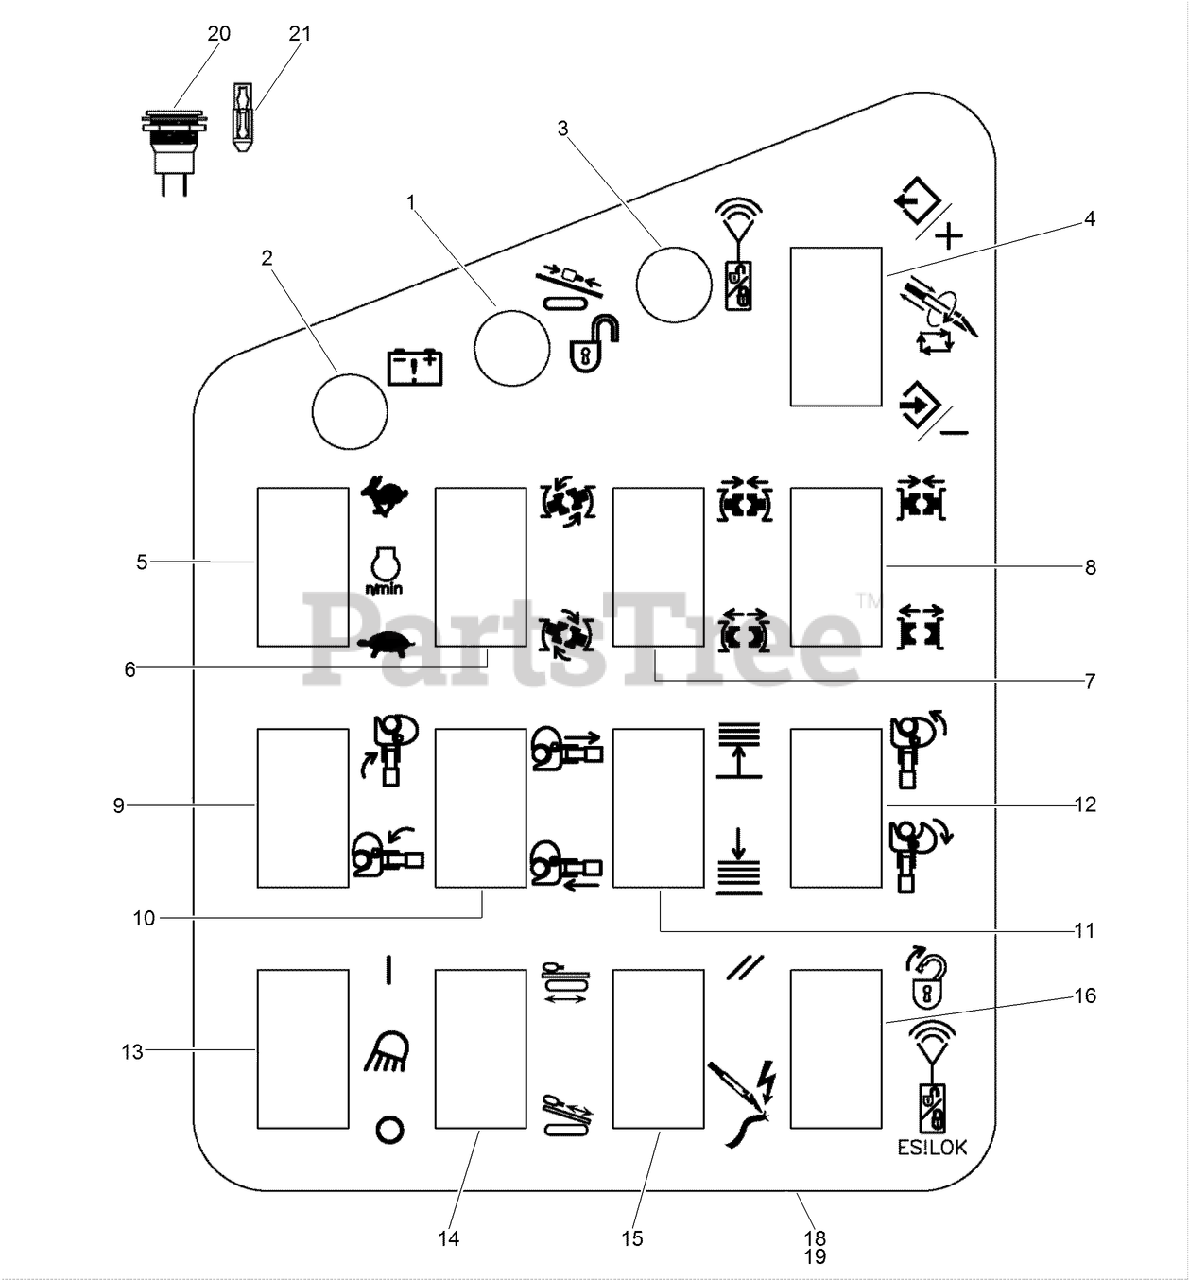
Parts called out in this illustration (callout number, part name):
1	LENS-DOME, FLUTED GREEN (TYPE T2)
2	LENS-DOME, FLUTED RED (TYPE T-2)
3	LENS-DOME, FLUTED AMBER (TYPE T2)
4	SWITCH-ROCKER, 2 POLE
5	SWITCH-ROCKER, 2 POLE
6	SWITCH-ROCKER, 2 POLE
7	SWITCH - Rocker, On - Off - (On) 2 Pole
8	SWITCH - Rocker, On - Off - (On) 2 Pole
9	SWITCH-ROCKER, 2 POLE
10	SWITCH-ROCKER, 2 POLE
11	SWITCH-ROCKER, 2 POLE
12	SWITCH-ROCKER, 2 POLE
13	SWITCH-ROCKER, 2 POLE (ON/OFF)
14	SWITCH-ROCKER, 2 POLE (ON/OFF)
15	SWITCH-ROCKER, 1 POLE (ON)OFF/ON(OFF)
16	SWITCH-ROCKER, 1 POLE (ON)OFF/ON(OFF)
19	PLATE - Cover, Left Console
20	TYPE T-2 SOCKET ASM
21	BULB-TYPE T-2, 12VOLT
